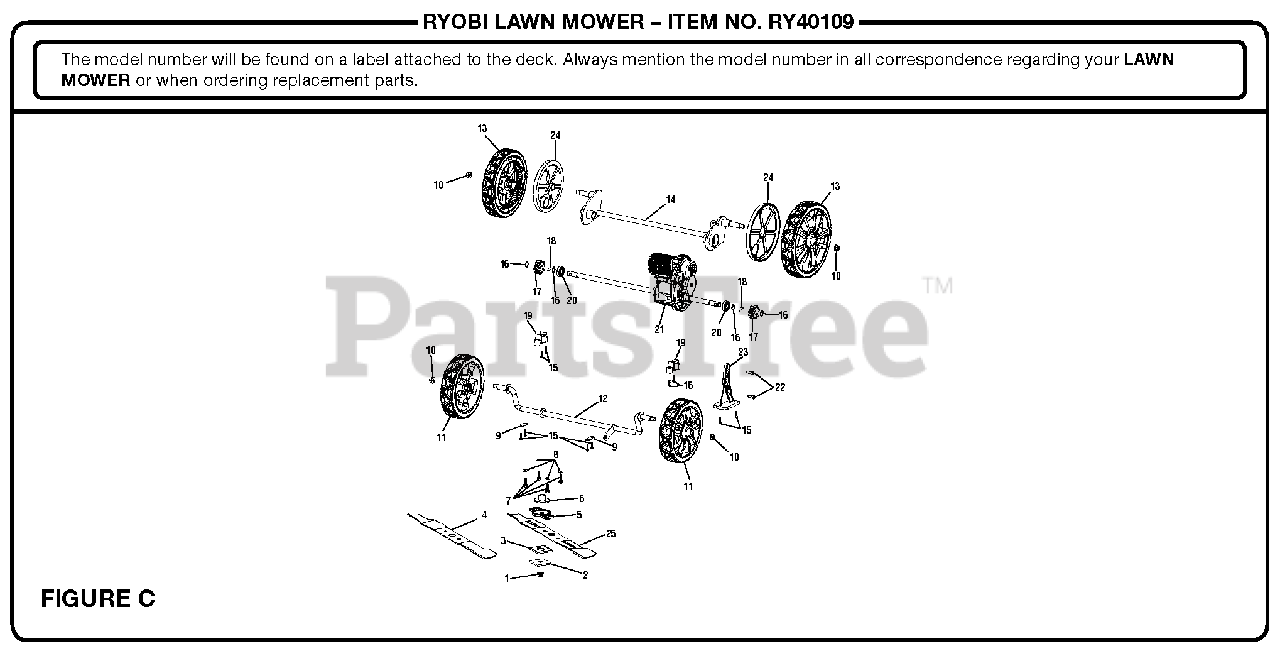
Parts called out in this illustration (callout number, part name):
1	Hex Nut (M10, Flange)
2	Blade Retainer
4	Mulching Blade
5	Blade Holder
6	Motor Shaft Bushing
7	Bolt (M6 x 26 mm, Hex Hd.)
8	Washer (ID6.2 x OD15 x 0.08t)
9	Axle Pressure Plate
10	Lock Nut (3/8-16, Flange)
11	Front Wheel Assembly
12	Front Wheel Axle
13	Rear Wheel Assembly
14	Rear Wheel Axle w/Rotation Plate
15	Screw (M4 x 20 mm, T20 Torx Pan Hd.)
16	Retaining Ring
17	Drive Gear
18	Gear Shaft
19	Mounting Plate
20	Ball Bearing (OD28.6 x ID12.7 x 8)
21	Transmission Assembly
23	Transmission Holder
24	Wheel Cover
25	Bagging Blade
